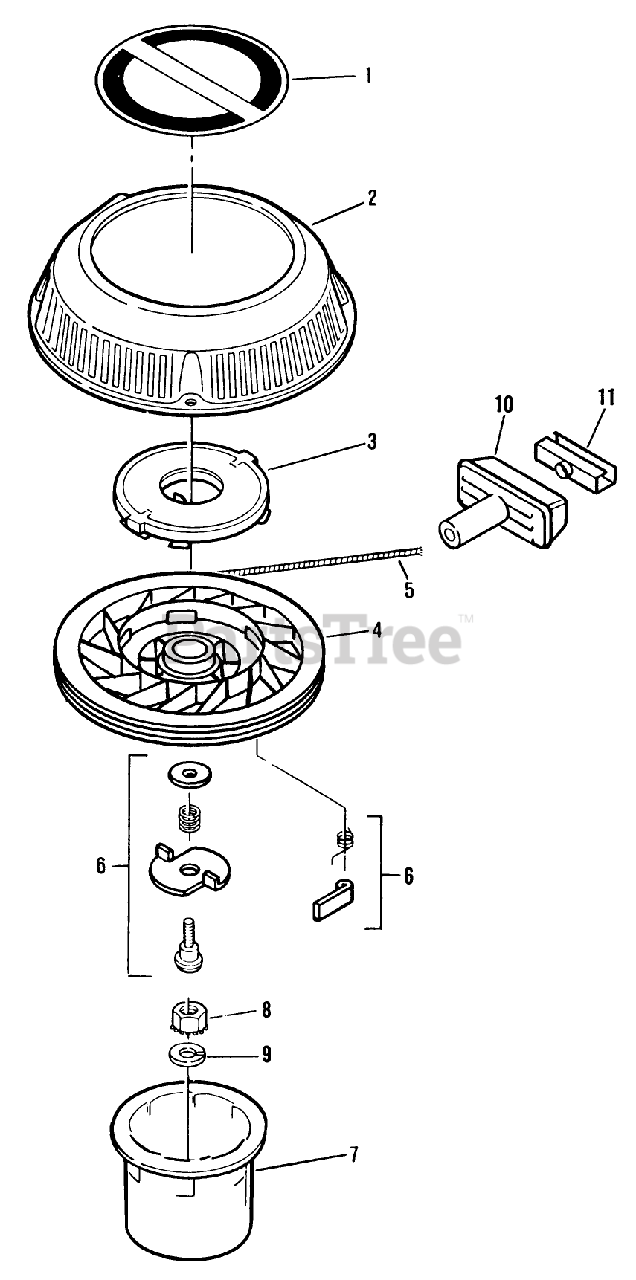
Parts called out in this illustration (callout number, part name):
4	PULLEY
6	DOG KIT
7	HUB-STARTER E COMM.
8	NUT
11	CLIP-STARTER
